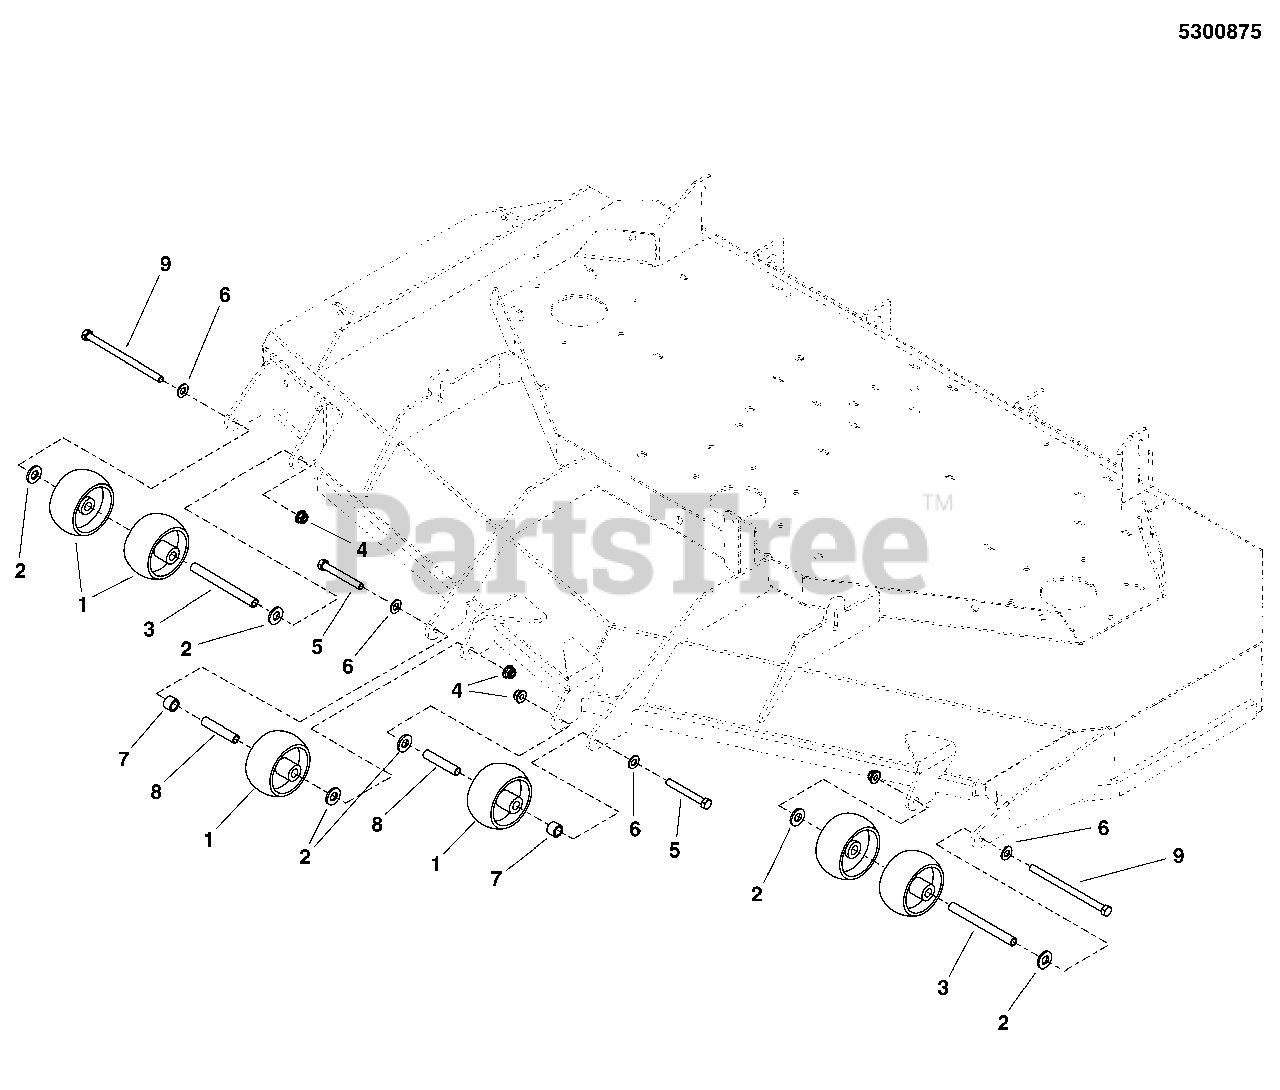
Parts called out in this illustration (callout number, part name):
1	GAUGE WHEEL
2	WASHER, 1/2 GD9 YZ
3	SPACER, .38 X .50 X 5.06
4	NUT, 3/8-16 HEX SIDELOCK
5	BOLT, 3/8-16 X 3-1/2 GD5 YZ
6	WASHER, 3/8 SAE
7	SPACER, .38 X .50 X 2.50, CZ
8	SPACER, .51 X .75 X .56
9	BOLT, 3/8-16 X 6 GD5 YZ
